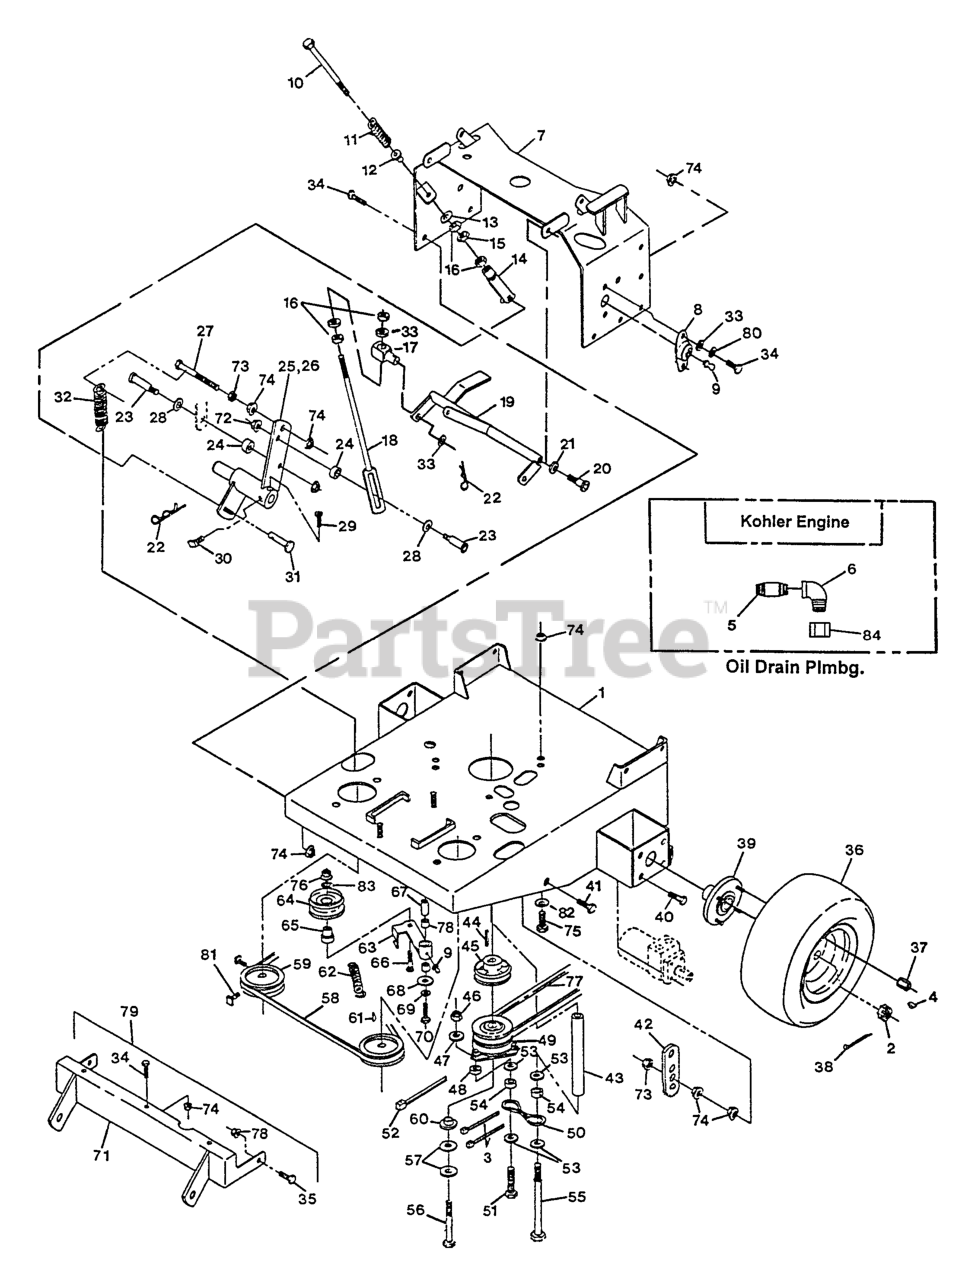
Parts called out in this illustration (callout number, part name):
1	Engine Deck Weldment
3	TIE-CABLE
4	KEY-WOODRUFF
5	NIPPLE,PIPE
6	ELBOW-90 DEG
8	FLANGE MTG, SIDE
10	BOLT-RETURN, NEUTRAL
11	SPRING-RETURN, NEUTRAL
12	BUSHING-FLANGED
14	YOKE-ADJUSTABLE
20	SCREW-HSH
22	PIN-COTTER
23	SCREW-HSH
26	WLD,LH CONTROL ARM
30	SCREW-SET
31	PIN-CLEVIS
32	SPRING-EXTENSION
38	PIN-COTTER
41	BOLT-TAP, HH
42	TAB-SPRING, EXTENSION
52	TIE-PLASTIC
54	SPACER,CLUTCH ANCHOR
55	SCREW-HH
57	WASHER-SPRING
58	BELT-HYDRO TRANS DR
59	SHEAVE - PUMP
60	BUSHING,CLUTCH KEEPER
62	SPRING-EXTENSION
63	IDLER ARM ASM
65	BUSHING-IDLER
67	BUSHING
71	WLD,SULKY HITCH
77	Belt/Shield Kit (60")
78	SLEEVE-BEARING
79	Hitch, Sulky
80	WASHER-LOCK
81	SCREW-SET
82	WASHER-SPRING
84	CAP-HEX
